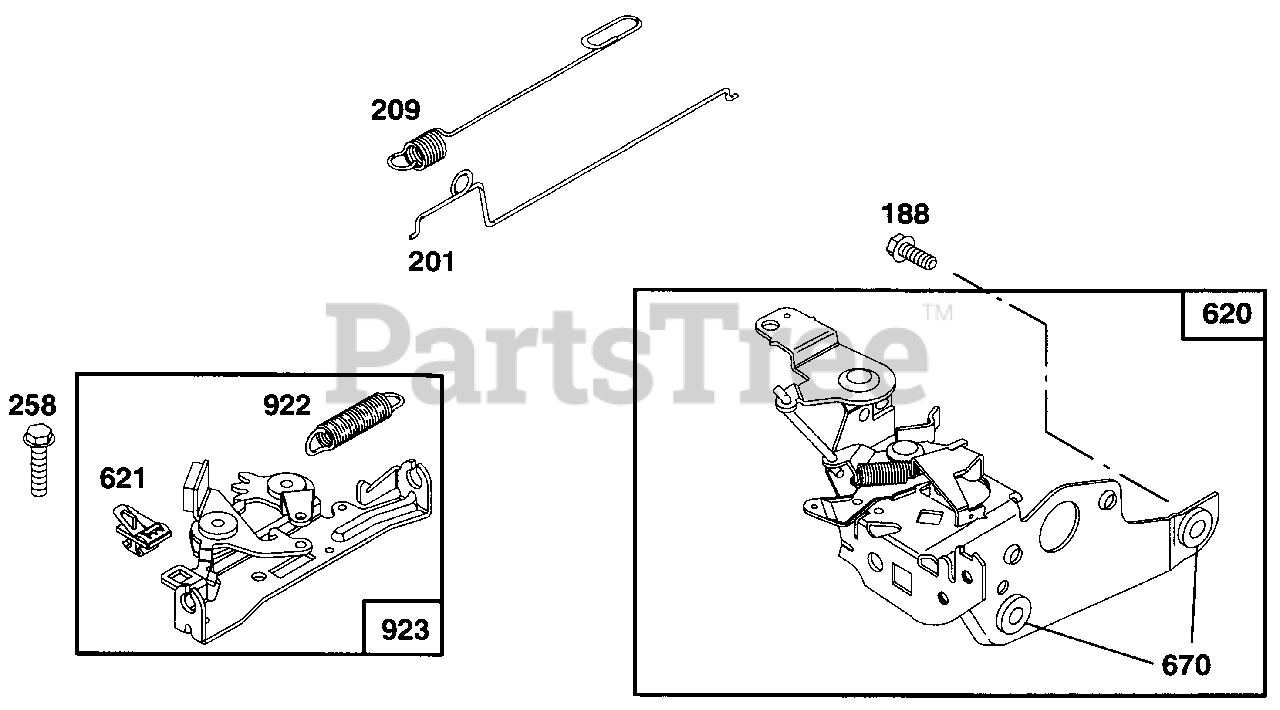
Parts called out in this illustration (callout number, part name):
188	Screw-Hex. Head
201	Link-Governor
209	Spring-Governor
258	Screw-Hex. Head
620	Bracket-Carburetor
621	Switch-Stop
670	Spacer-Bracket
922	Spring-Brake
923	Brake Assembly
